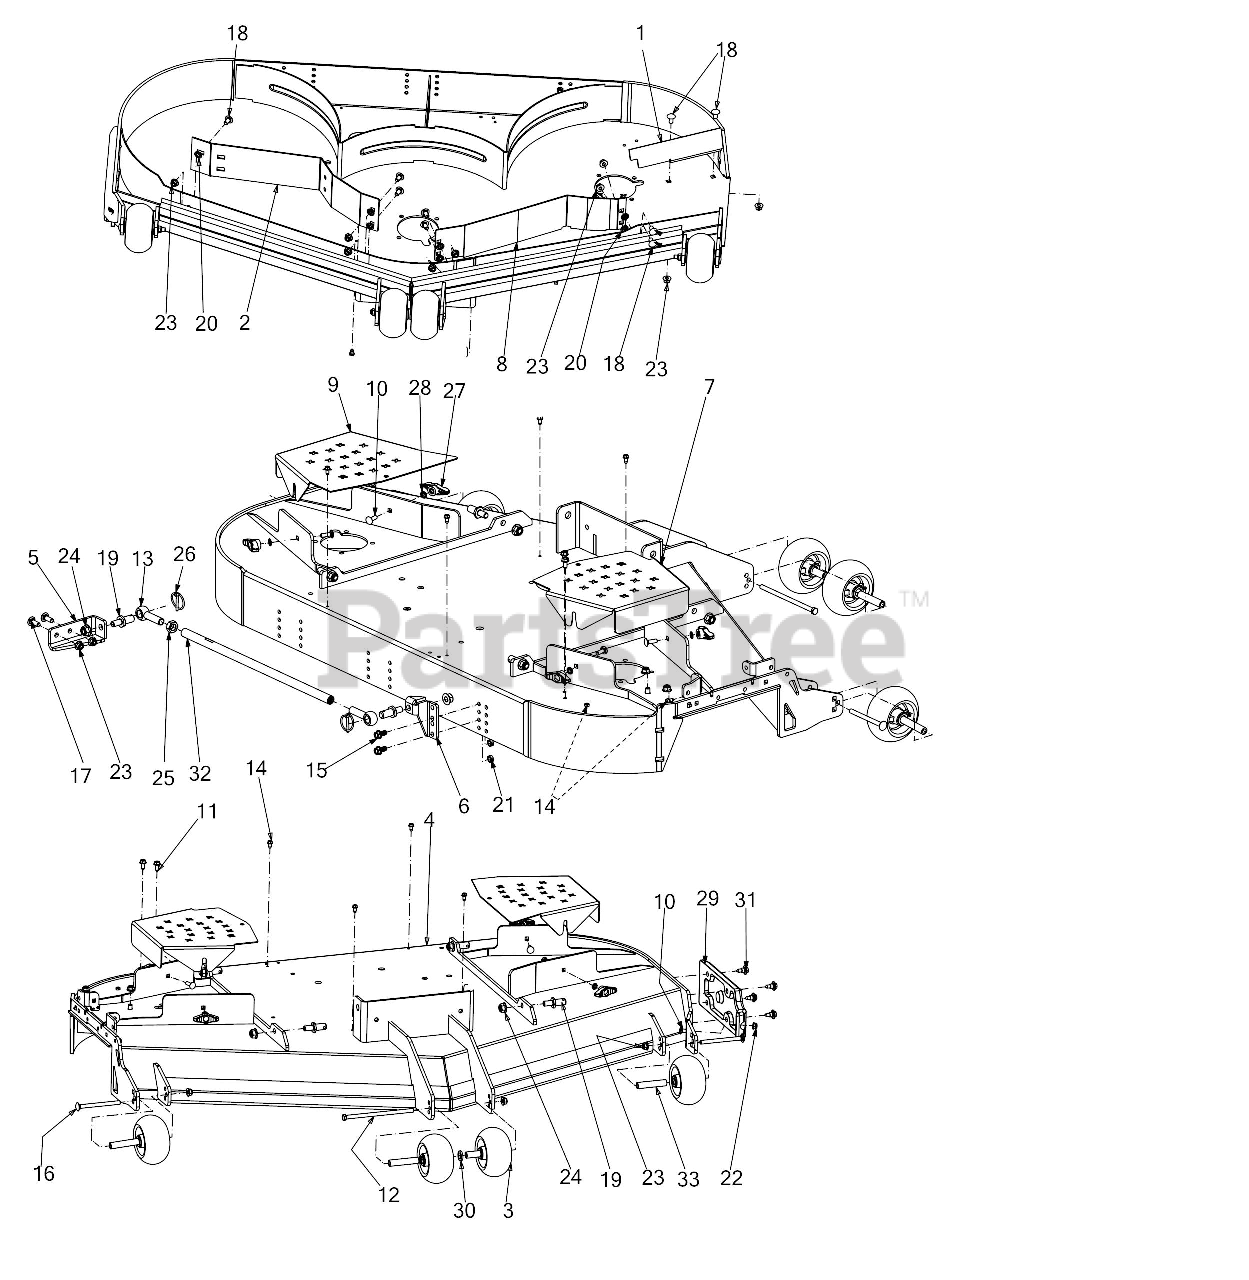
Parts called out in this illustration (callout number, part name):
3	WHEEL ASSEMBLY 5"
4	60" FAB DECK SHELL ASSEMBLY
5	STABILIZER MOUNTING BRACKET
6	REAR STABILIZER BRACKET
7	DECK BELT COVER
8	DECK BAFFLE
10	CARRIAGE BOLT 5/16-18 x 1.00
11	SCREW 5/16-18 x .750
12	SCREW 3/8-16 x 7.25 GR5
13	BOLT 5/8-16 x 2.63
14	SCREW 1/4-20 X.500
15	SCREW 3/8-16 x 3/4
16	CARRIAGE BOLT 3/8-16 x 4.25 GR5
17	CARRIAGE BOLT 3/8-16 x 1.00 GR5
18	CARRIAGE BOLT 3/8-16 x .75
21	JAM LOCK NUT
22	FLANGE LOCK NUT 5/16-18
25	HEX NUT
27	WING KNOB 5/16-18
29	DECK SKID PLATE (LH)
30	FLAT WASHER .632X1.00X.16
31	SHOULDER SCREW .43X.29X5/16-18 TT
33	WHEEL SPACER .38ID x 3.04LG
